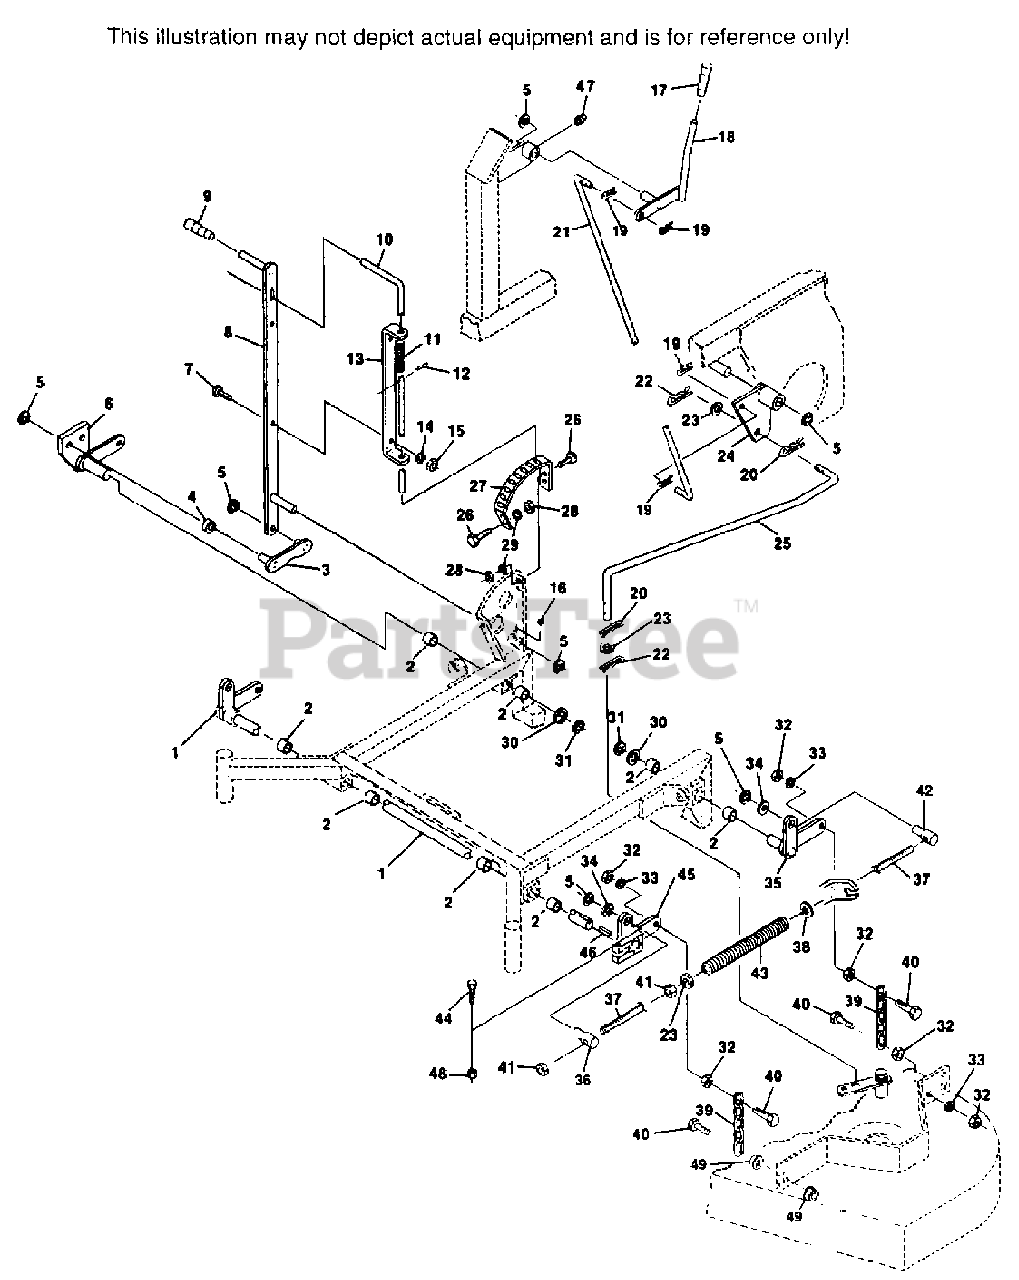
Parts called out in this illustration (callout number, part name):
1	LIFT ARM WELDMENT
2	BUSHING
3	LIFT LINK
4	BUSHING
5	RETAINING RING, 5/8" EXTERNAL "E"
6	BELLCRANK, LIFT - RIGHT REAR
8	HEIGHT ADJUSTMENT LEVER(INCLUDES GRIP)
9	GRIP, LIFT LEVER
10	ROD, CUTTER DECK LOCK
11	SPRING, DECK LIFT INDEX
12	ROLL PIN, 5/32 X 3/4"
13	LOCK ROD GUIDE
16	GREASE FITTING
17	GRIP, BLADE CLUTCH LEVER
18	LEVER, CUTTER ENGAGEMENT(INCLUDES GRIP)
19	HAIR PIN, 1/16" DIA.
20	COTTER PIN, 3/32 X 1"
21	ROD, CUTTER ENGAGEMENT - UPPER
22	HAIR PIN, 1/8" DIA.
24	BELLCRANK, CUTTER ENGAGEMENT
25	ROD, CUTTER ENGAGEMENT - LOWER
27	STRIP, HEIGHT ADJUSTMENT
30	FLAT WASHER, 3/4 SPECIAL
31	RETAINING RING, 3/4" EXTERNAL "E"
35	BELLCRANK, LIFT - LEFT REAR
36	SWIVEL JOINT - RH
37	ADJUSTMENT STUD
38	FLAT WASHER, 5/8" ID
39	CHAIN
42	SWIVEL JOINT - LH
43	SPRING, DECK LIFT
45	BELLCRANK, LIFT - LEFT FRONT
46	KEY, 3/16 X 3/16 X 1"
47	GREASE FITTING
48	HEX NUT, 3/8-16 ELASTIC STOP
